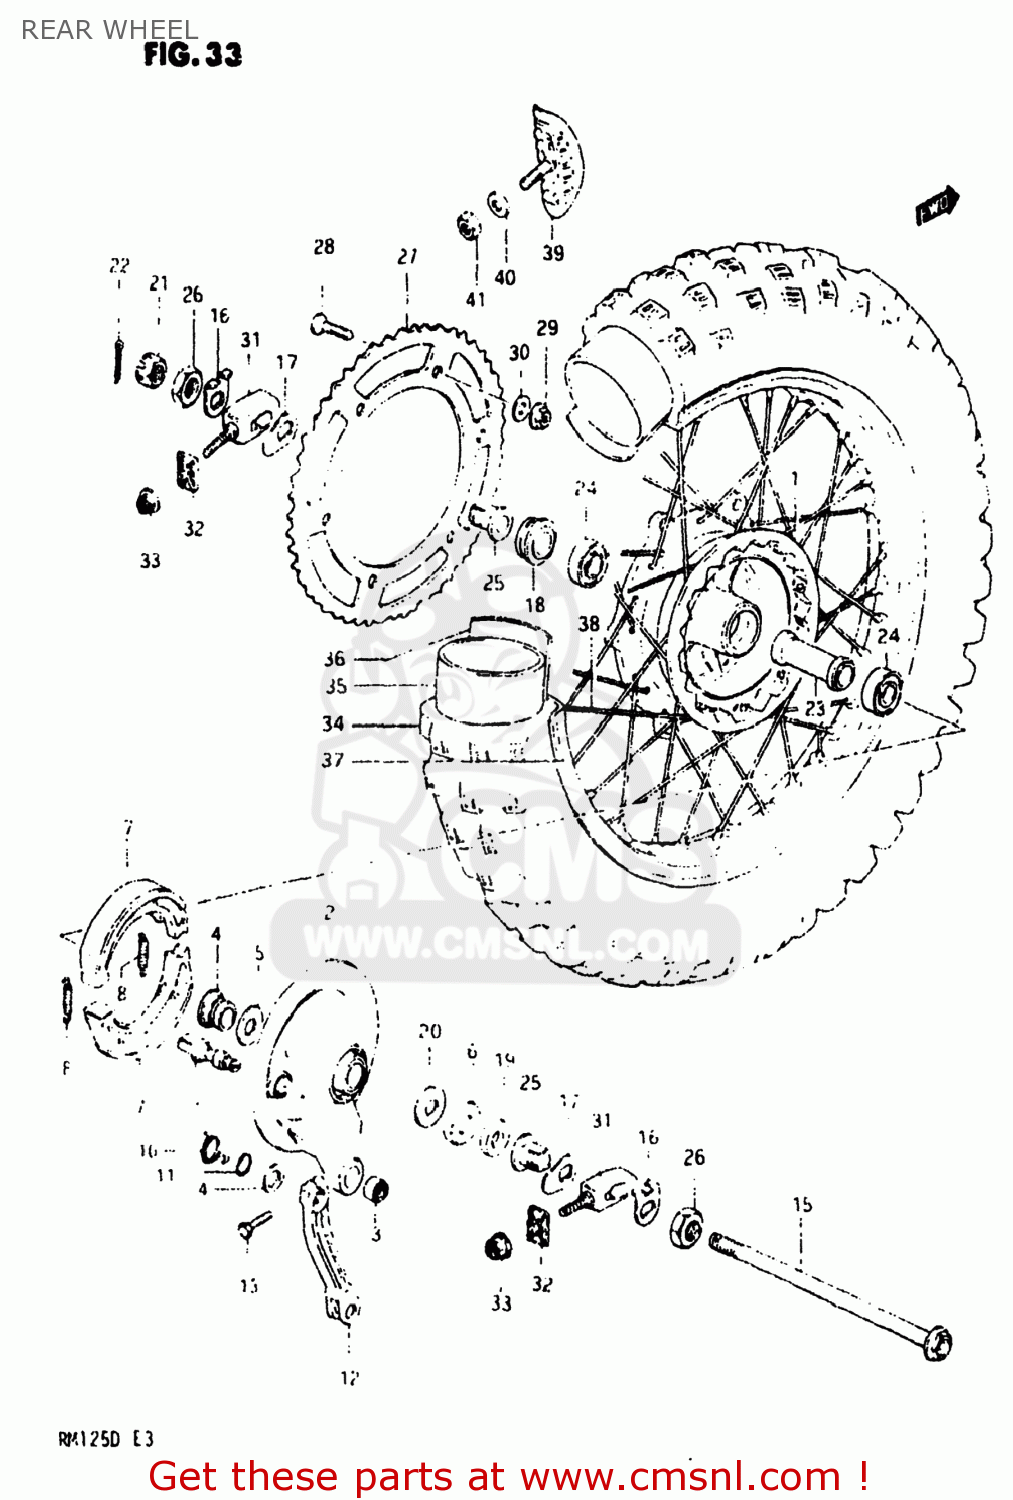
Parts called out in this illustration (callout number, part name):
1	DRUM,REAR HUB
2	PANEL SET,REAR HUB
3	SPHERICAL BRNG,TORQUE LINK
4	SPACER,RR BRAKE ANCHOR PANEL
5	SEAL,OIL(20X27X5)
6	CVR,RR BRAKE AHR PNL DUST SEAL
7	SHOE,BRAKE (MCA)
8	SPRING(L:34)
9	CAM,FR BRAKE
10	SPRING
11	O RING(D:2.5,ID:11.4)
12	LEVER,RR BRAKE CAM
13	BOLT
14	WASHER(12.5X20X1)
15	AXLE,REAR
16	WASHER,CHAIN ADJUSTER GUIDE
17	WASHER,CHAIN ADJUST GUIDE
18	SPACER,RR AXLE,L
19	SPACER,REAR AXLE,RIGHT
20	WASHER,THRUST
21	NUT
22	COTTER PIN
23	SPACER
24	BEARING
25	SPACER,CHAIN ADJUSTER
26	NUT
27	SPROCKET,REAR
28	SCREW(8X33.5)
29	NUT
30	WASHER
31	ADJUSTER,CHAIN
32	PLATE,CHAIN ADJUSTER GUIDE,R
33	NUT
34	TIRE
35	TUBE ASSEMBLY,WHEEL,INNER
36	PROTECTOR,INNER TUBE
37	RIM,REAR WHEEL
38	SPOKE SET,REAR WHEEL
39	STOPPER,BEAD
40	WASHER
41	NUT
